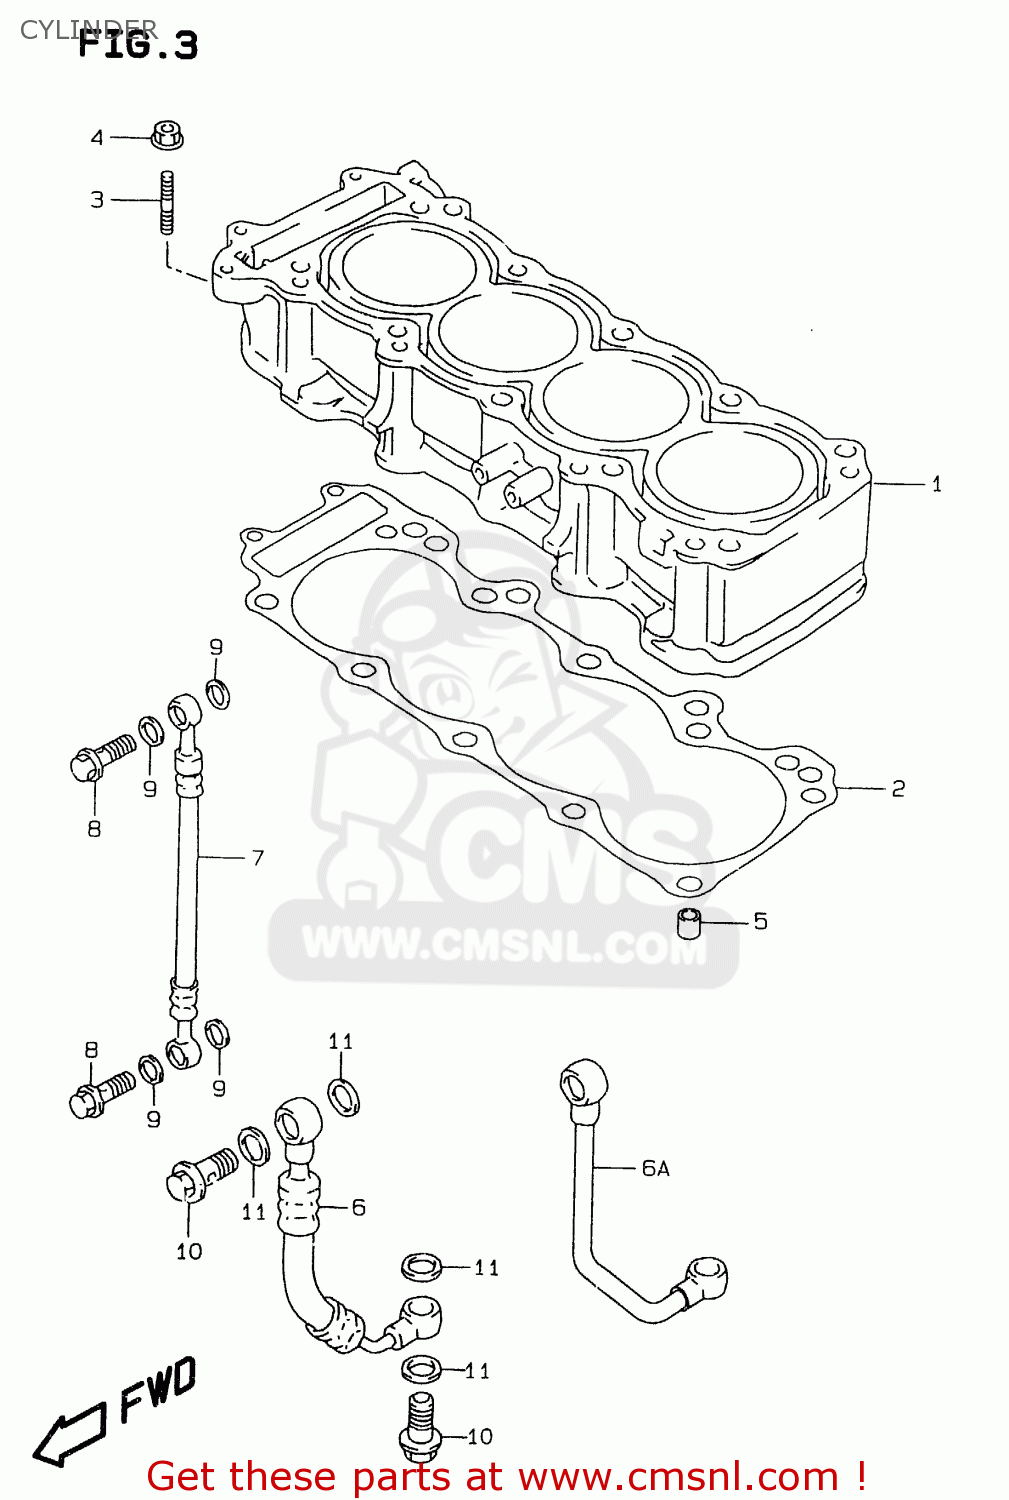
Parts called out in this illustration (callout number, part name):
1	CYLINDER
2	GASKET,CYLINDER(T:0.25)
3	STUD,M6X1X32
4	NUT
5	PIN
6	HOSE,OIL GALLERY
6A	PIPE COMP,CRANKCASE OIL
7	HOSE,CYLINDER HEAD OIL
8	BOLT UNION
9	GASKET(10.1X16X1) (NAS)
10	BOLT UNION
11	GASKET(14X20X1.5) (NAS)
